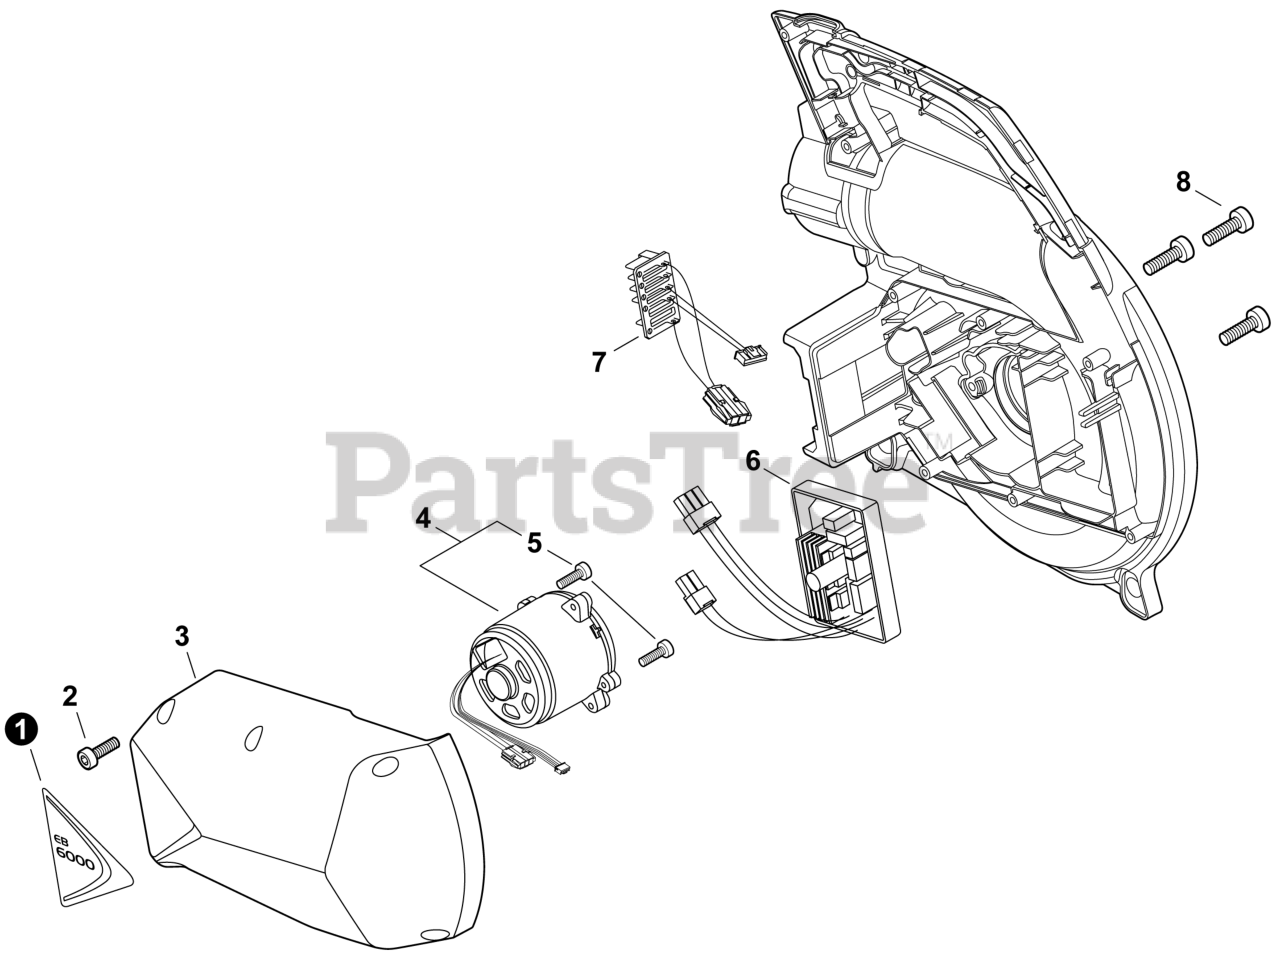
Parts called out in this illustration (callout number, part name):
1	LABEL - MODEL EB6000
2	BOLT, TORX 4x16
3	COVER, MOTOR
4	MOTOR ASSY
5	BOLT, TORX 4x12
6	CONTROL BOARD ASSY
7	TERMINAL, LEAD
8	BOLT, TORX 5x20
